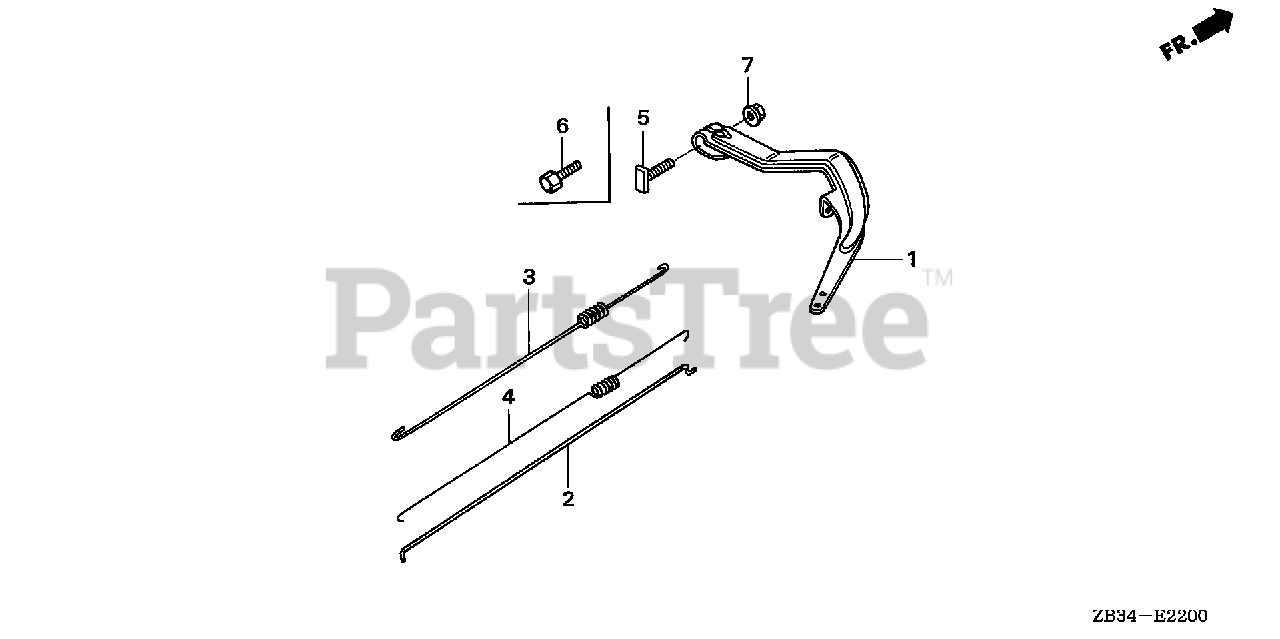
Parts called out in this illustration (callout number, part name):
1	ARM, GOVERNOR
2	ROD, GOVERNOR
3	SPRING, GOVERNOR
4	SPRING, THROTTLE RETURN
5	BOLT, GOVERNOR ARM
6	BOLT, HEX. (6X20)
7	NUT, FLANGE (6MM)
